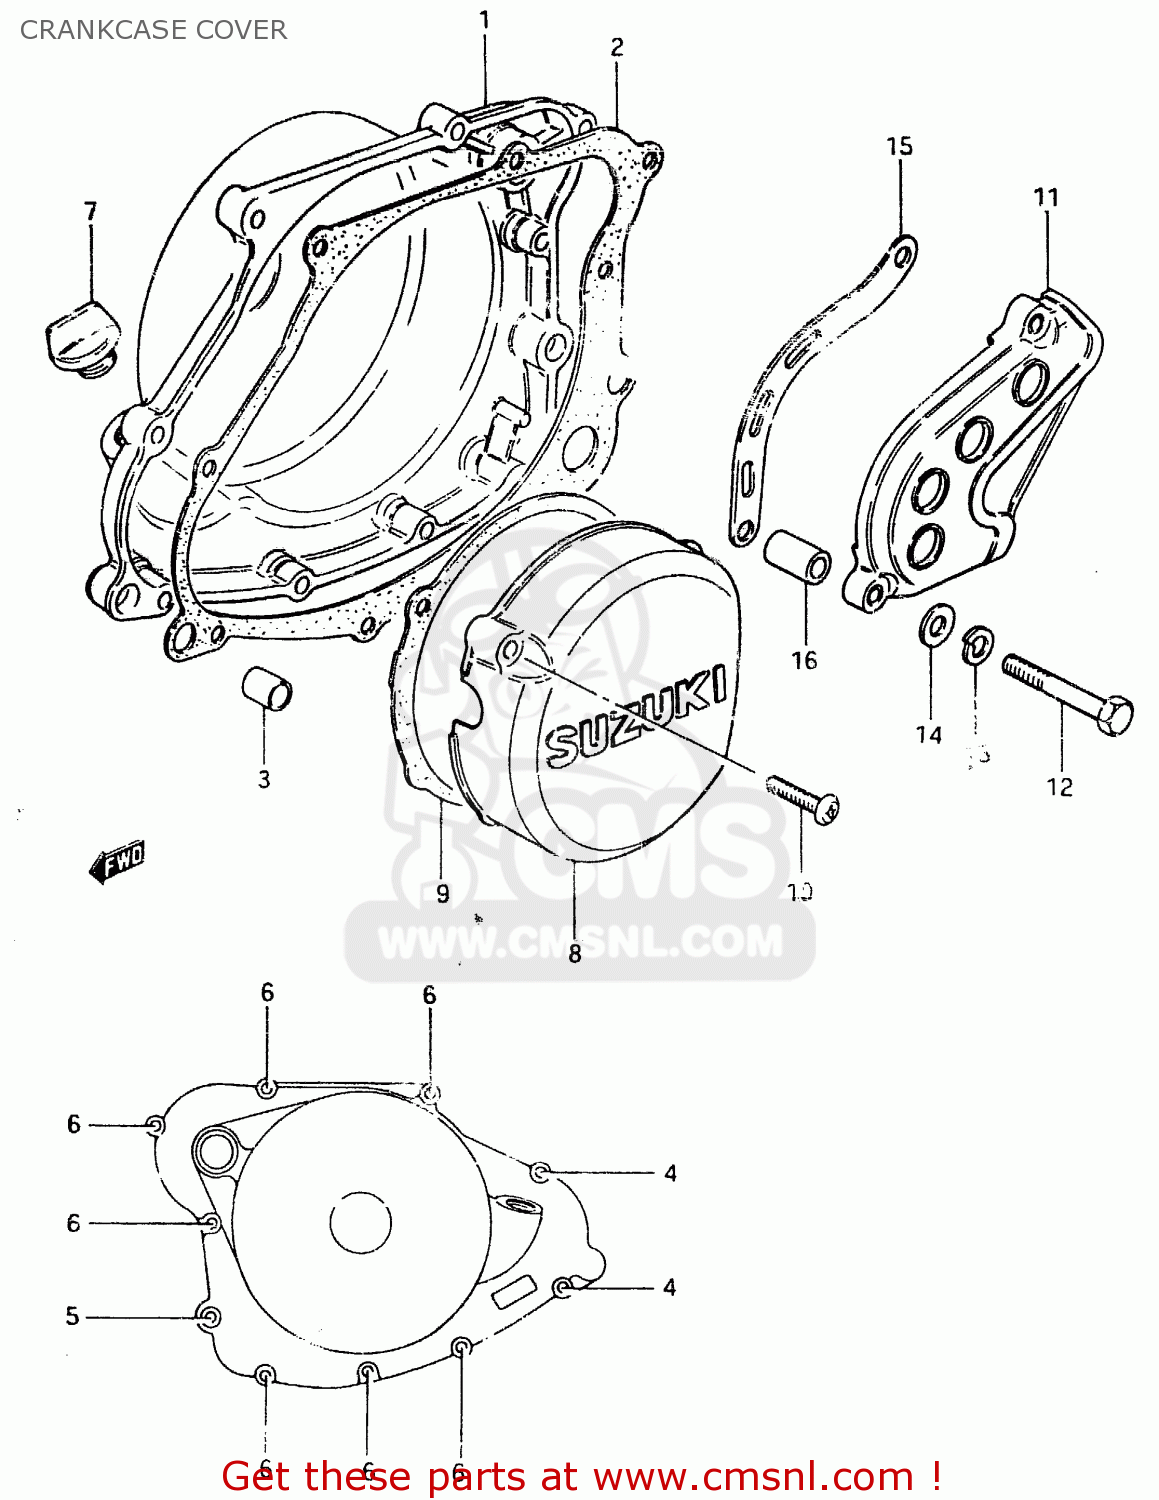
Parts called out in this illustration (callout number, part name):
1	COVER,CLUTCH
2	GASKET,CLUTCH COVER (MCA)
3	PIN
4	SCREW
5	SCREW
6	SCREW
7	PLUG,OIL FILTER
8	COVER,MAGNETO
9	GASKET,MAGNETO COVER (MCA)
10	SCREW
11	COVER,ENGINE SPROCKET
12	BOLT 8X55
13	LOCK WASHER
14	WASHER,8.5X16X
15	PLATE,FR CHAIN GUIDE
16	SPACER(8.6X16X24)
